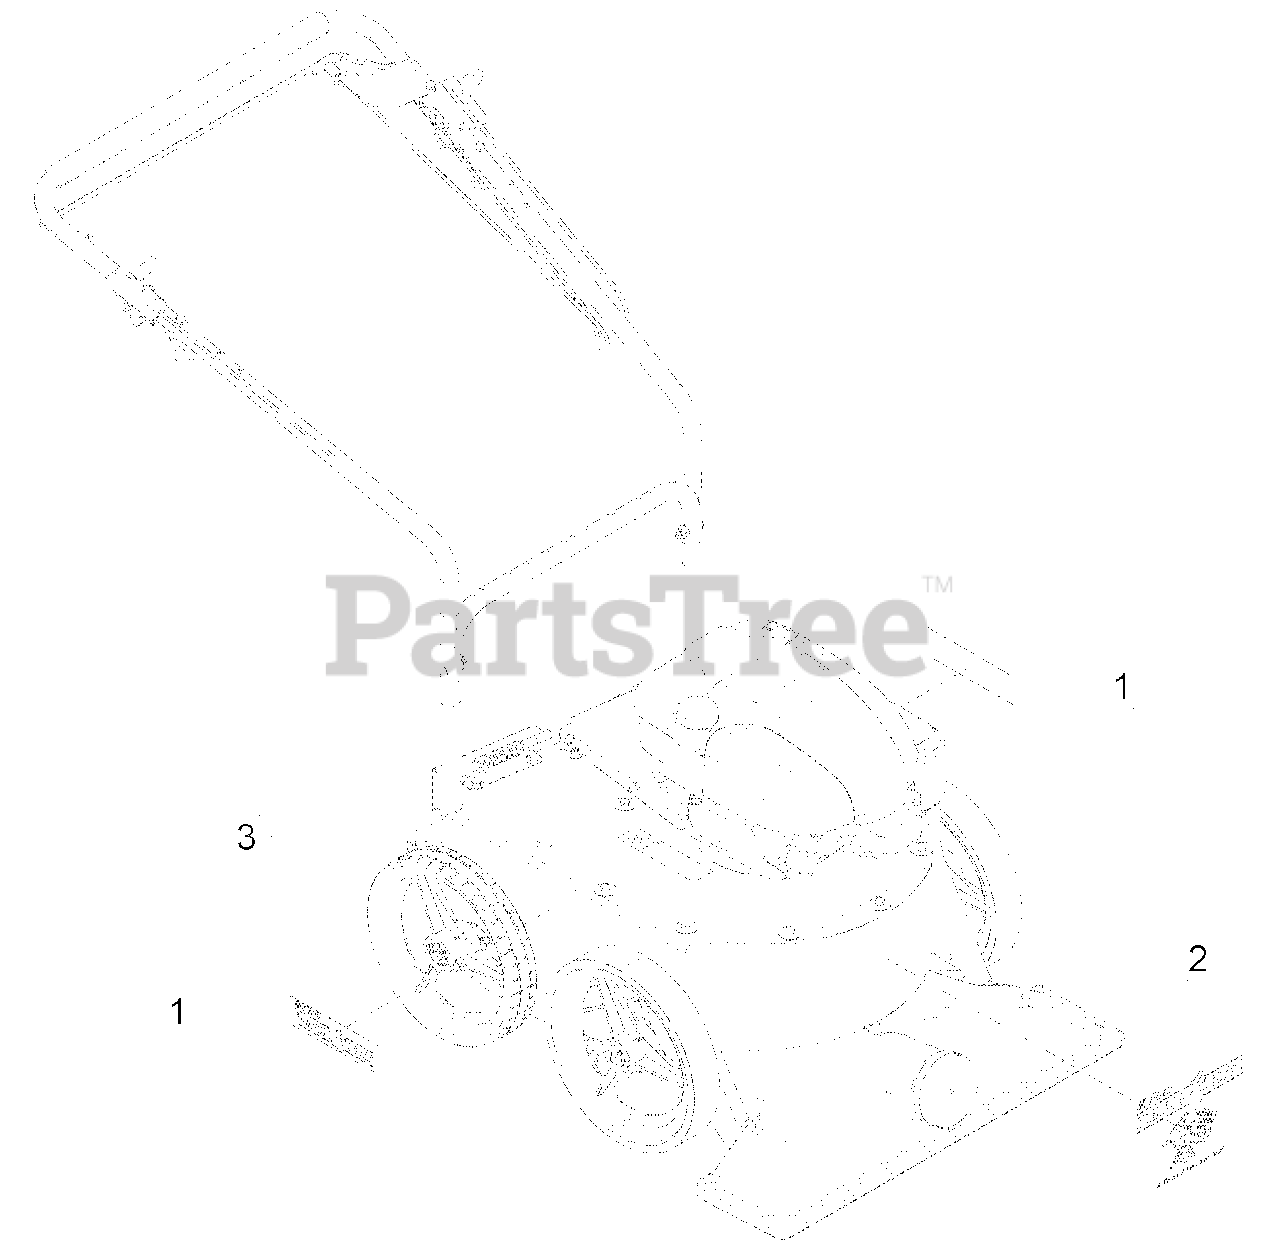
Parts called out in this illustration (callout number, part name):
1	DECAL, ECHO BEARCAT
2	DECAL, ECHO BEARCAT
3	DECAL, MODEL WV190S
